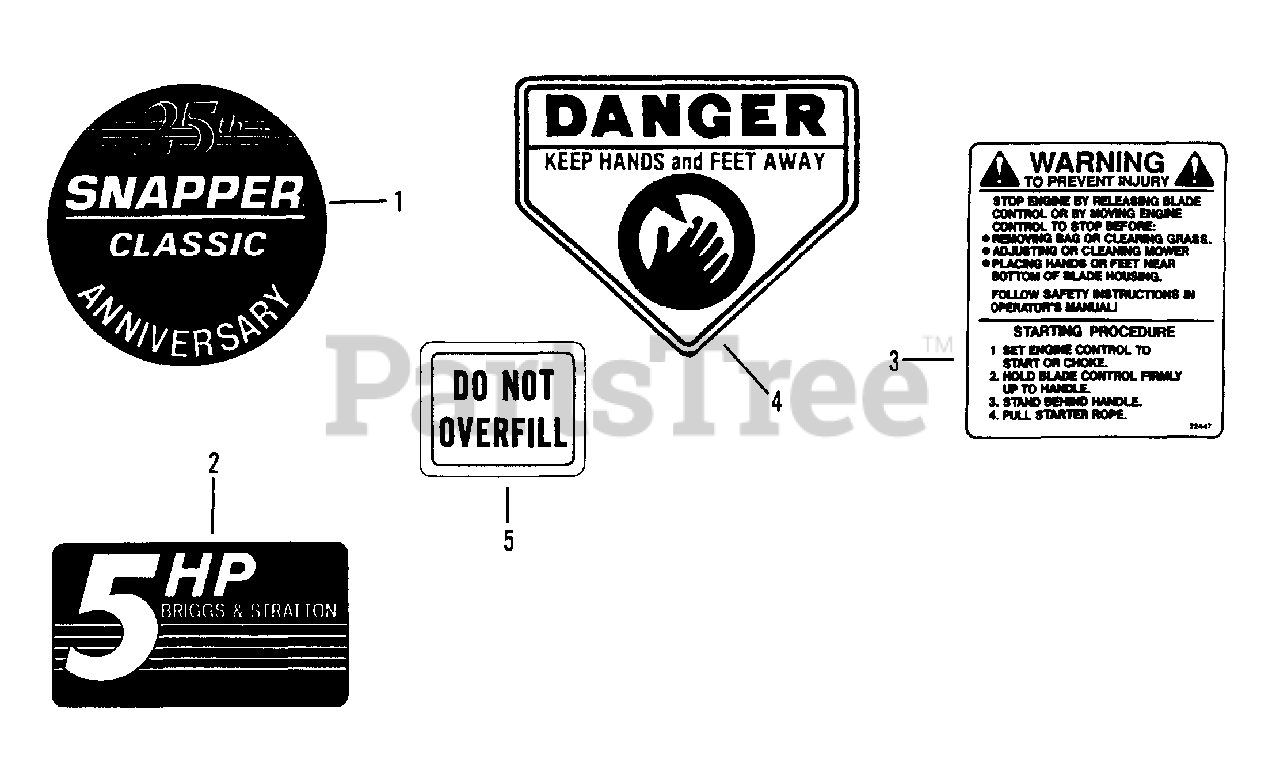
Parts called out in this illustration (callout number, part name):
1	DECAL, Recoil
2	DECAL, Housing
3	DECAL, Warning
4	DECAL, Danger
5	DECAL, "DO NOT OVERFILL"
